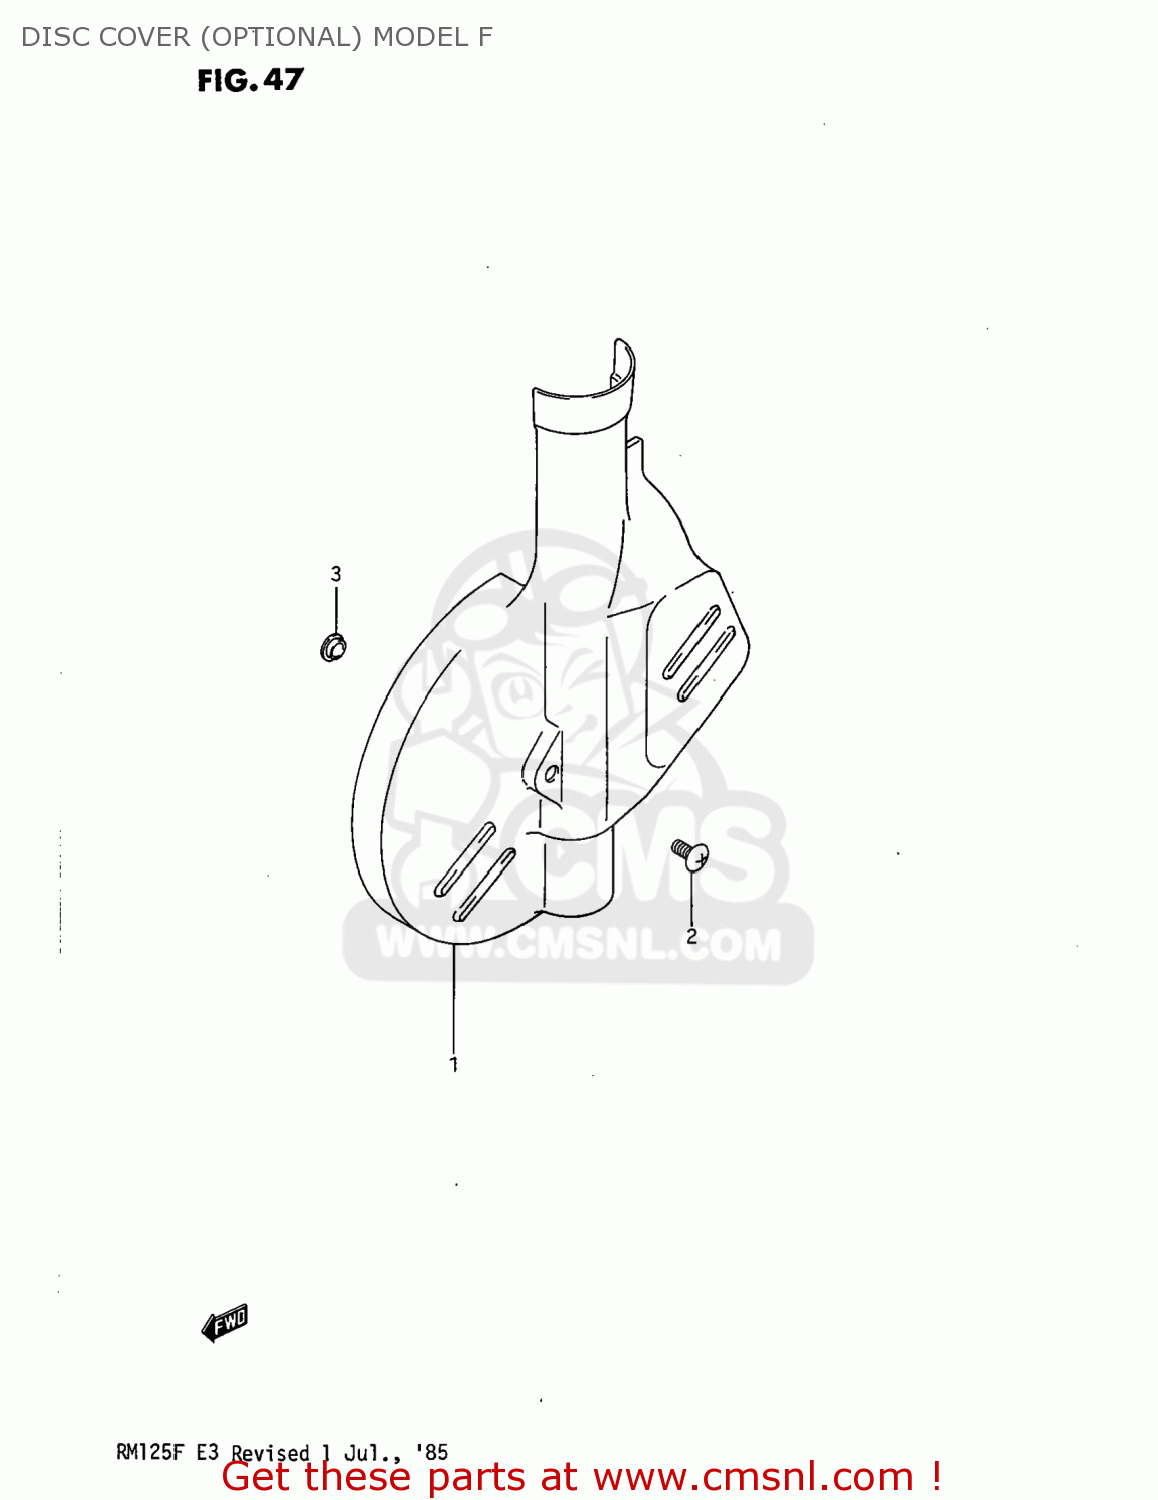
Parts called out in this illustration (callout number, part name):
1	COVER,FRONT BRAKE DISC
2	SCREW(8X12)
3	WASHER
